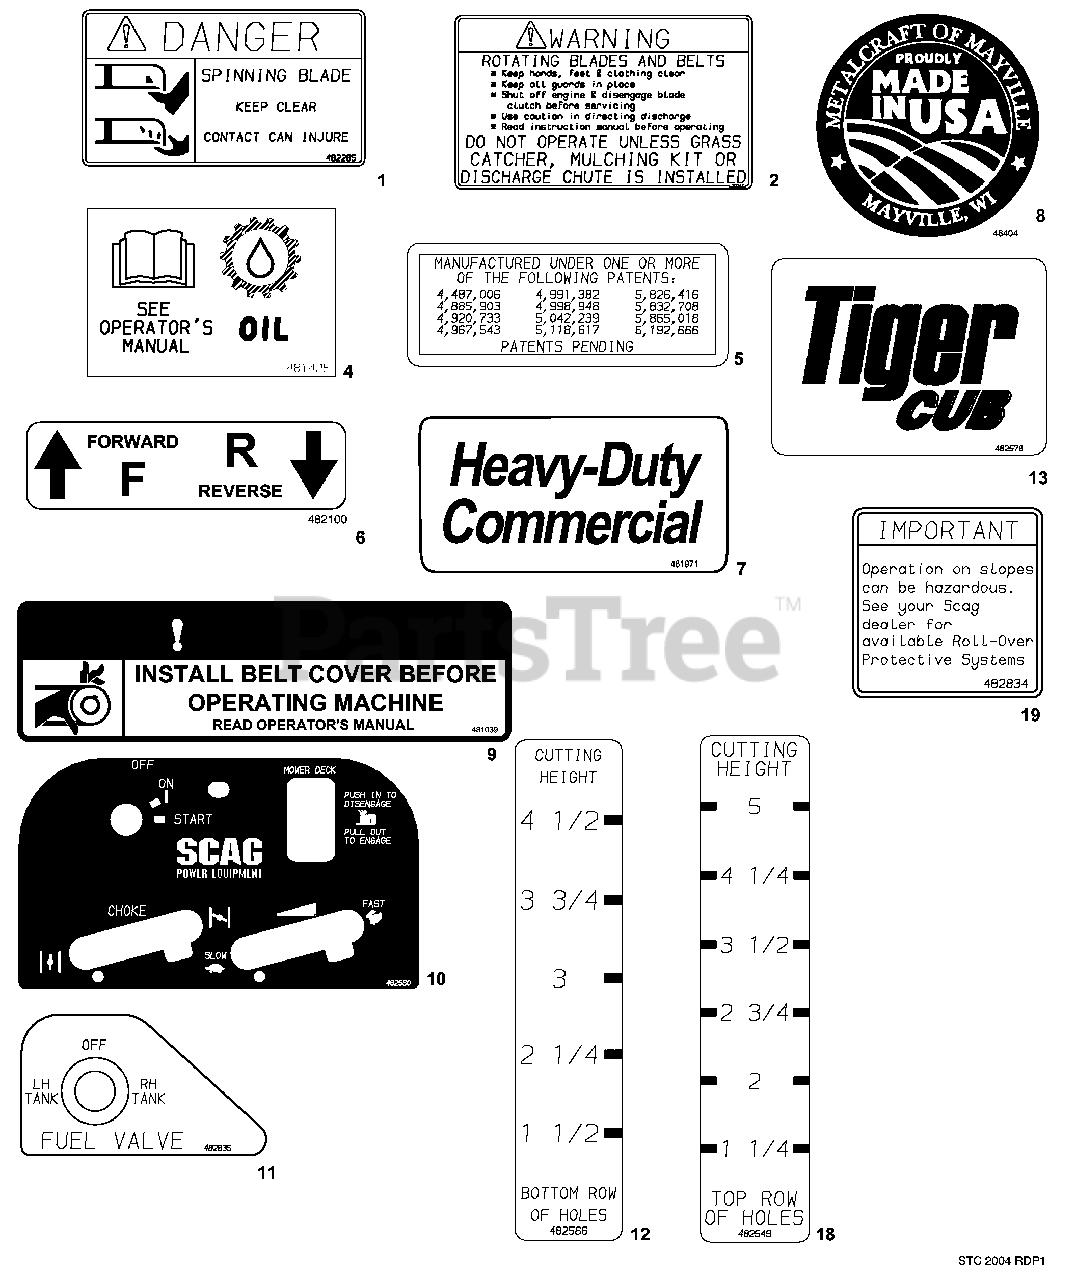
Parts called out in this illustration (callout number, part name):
1	Decal, Danger-Spining Blades
2	Decal, Warning-Rotating Blades
4	Decal, Oil
5	Decal, Patents
6	Decal, Traction Control
7	Decal, Heavy Duty Commercial
8	Decal, Metalcraft - Made in USA
9	Decal, Belt Cover
10	Decal, Instrument Panel
11	Decal, Fuel Valve Position
12	Decal, Cutting Height Bottom Row of Holes
13	Decal, Tiger Cub
18	Decal, Cutting Height Top Row of Holes
19	Decal, ROPS
